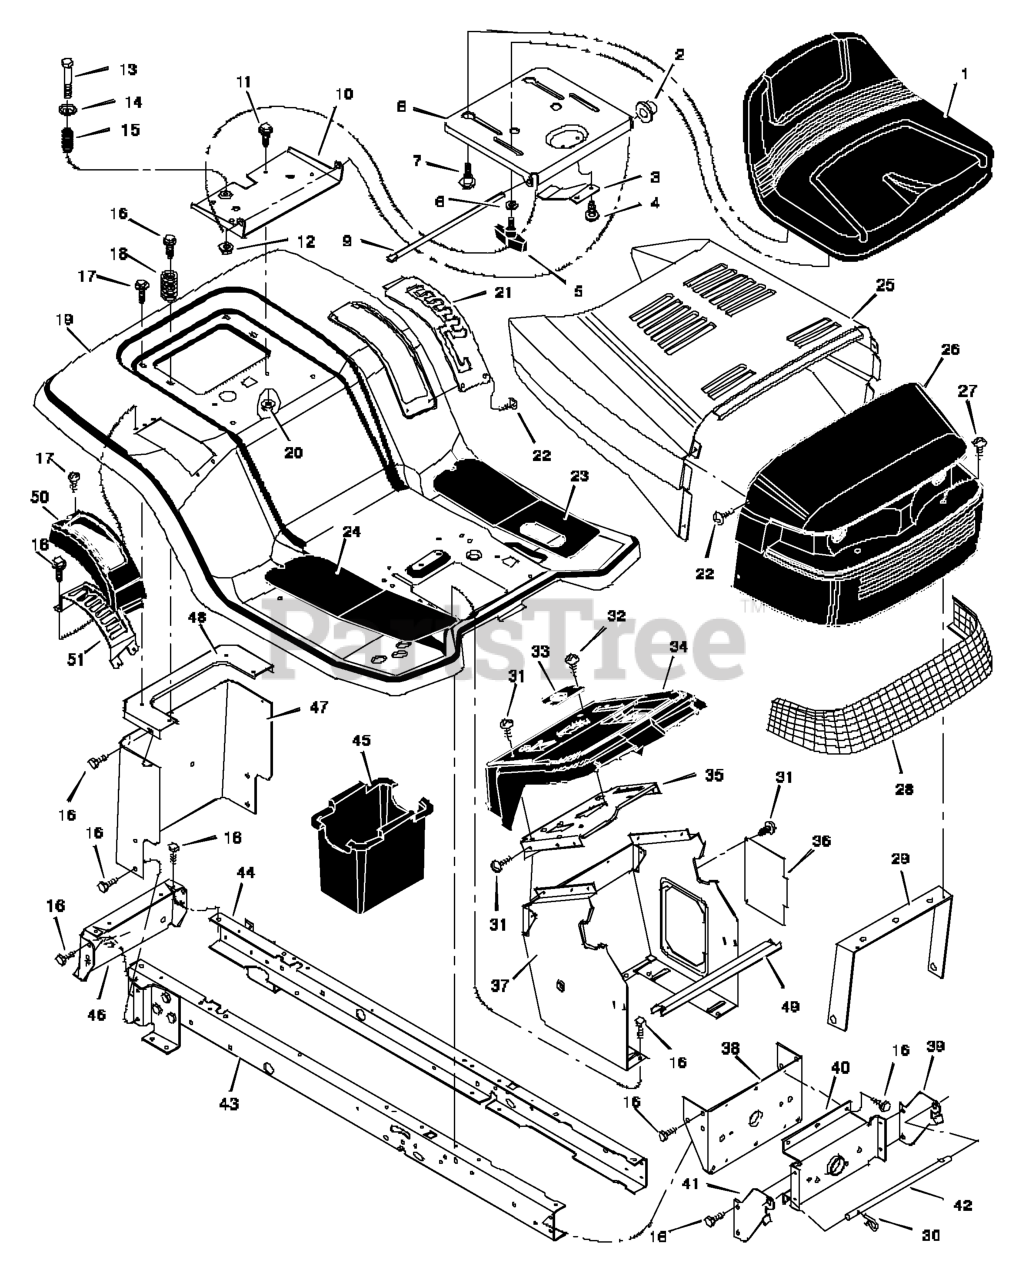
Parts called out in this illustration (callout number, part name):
1	Seat
2	Cap, Push On
5	Bolt, Wing
6	Washer
7	Bolt, Shoulder
8	Support, Seat
9	Rod, Pivot
10	Bracket, Pivot
11	Bolt
13	Bolt, Shoulder
15	Spring
19	Deck, Seat
20	Nut
21	Plate, Index
23	Mat, Left
24	Mat, Right
25	Hood
26	Grille Assembly
29	Brace, Grille
30	Pin, Hair
31	Screw
33	Bearing, Steering
35	Plate, Dash
36	Panel, Access
37	Support, Dash
38	Bracket, Rear Hanger
39	Support, Left Grille
40	Axle, Hanger
41	Support, Right Grille
42	Rod, Pivot
43	Frame, Right
44	Frame, Left
45	Container, Battery
46	Plate, Hitch
47	Panel, Rear
50	Cover, Shift Gate
51	Gate, Shift
